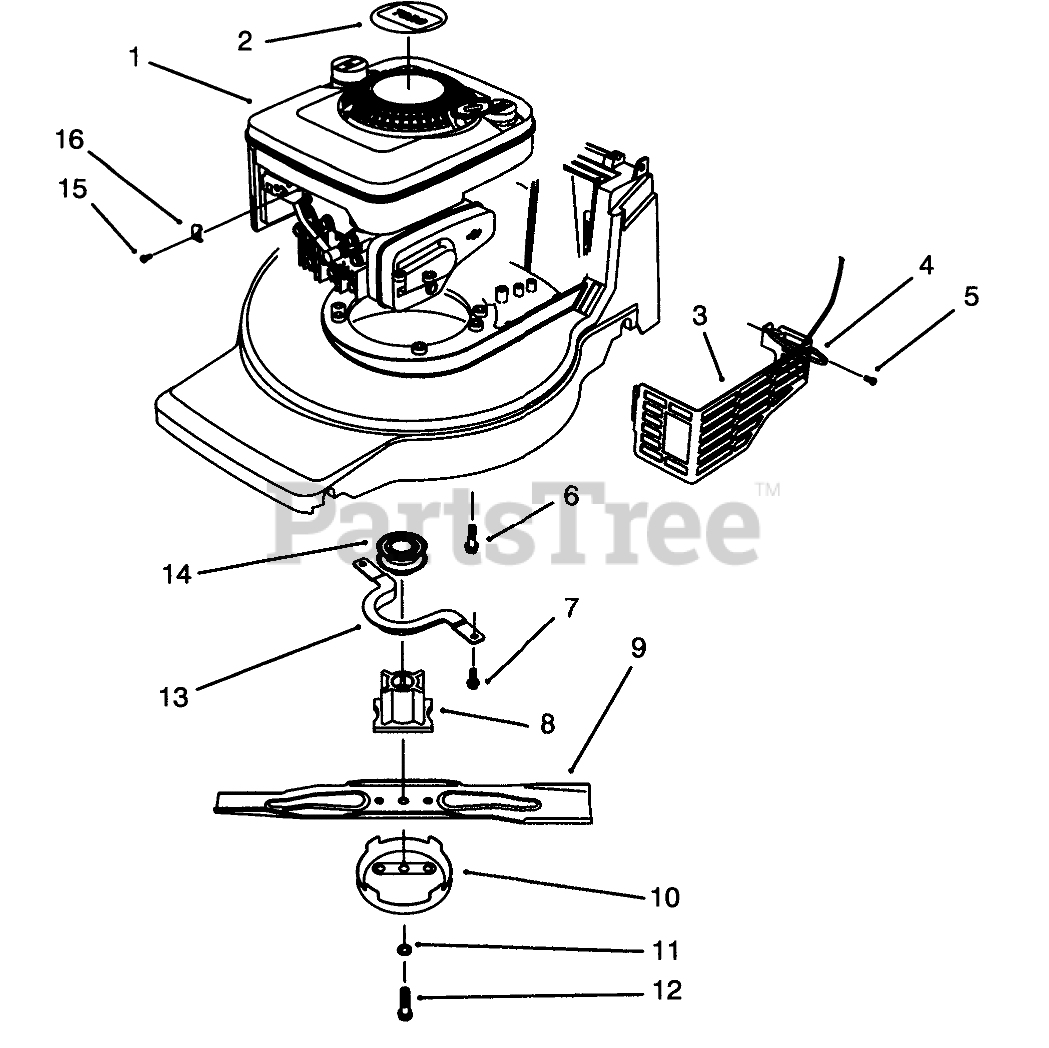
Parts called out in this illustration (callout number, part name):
1	Engine-B&S Quantum
2	DECAL - RECOIL
3	SHIELD-MUFFLER
4	TIE-CABLE
5	Screw-Muffler
6	SCREW-HWH
7	SCREW-HWH
8	BLADE RETAINER - 25 MM
9	Blade-48cm
10	CUP-SCALP, ANTI
11	WASHER-LOCK
12	BOLT-BLADE
13	Guide-Belt
14	PULLEY-DRIVE, ZONE START
15	CLAMP SCREW F/W ENGINE
16	CLAMP-CASING
